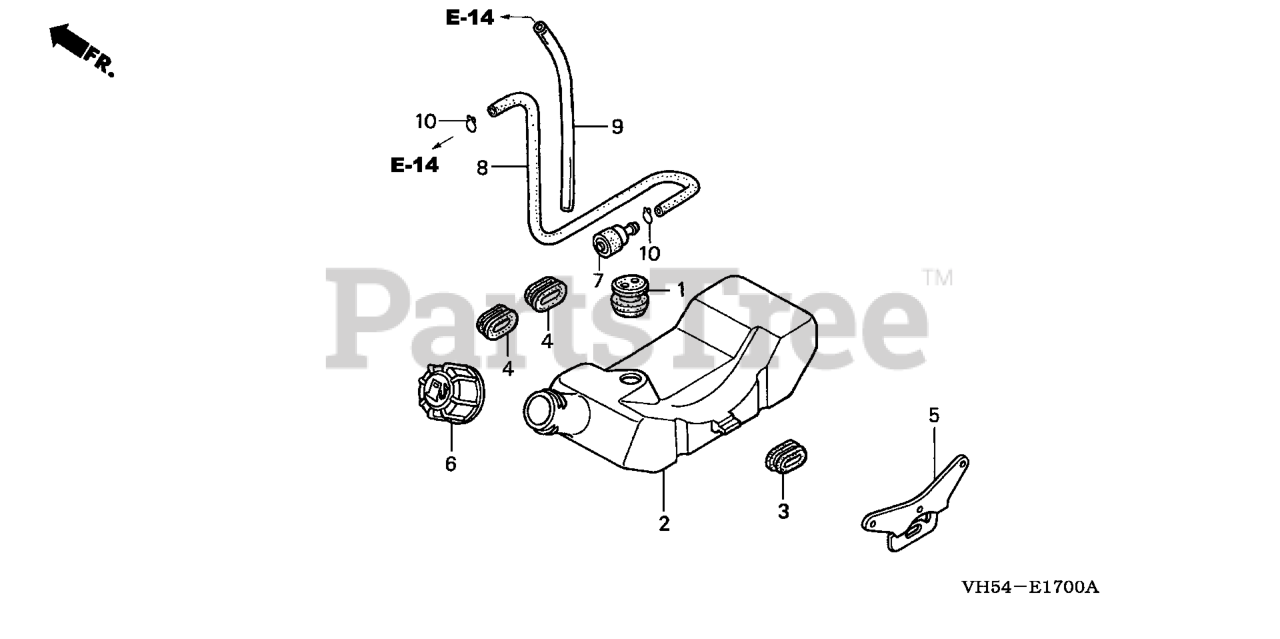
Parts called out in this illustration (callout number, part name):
1	GROMMET, FUEL TUBE
2	TANK, FUEL
3	RUBBER A, TANK MOUNTING
4	RUBBER A, TANK MOUNTING
5	STAY, FUEL TANK
6	CAP ASSY., FUEL TANK
7	FILTER, FUEL
8	TUBE, FUEL
9	TUBE, FUEL RETURN
10	CLIP, TUBE
